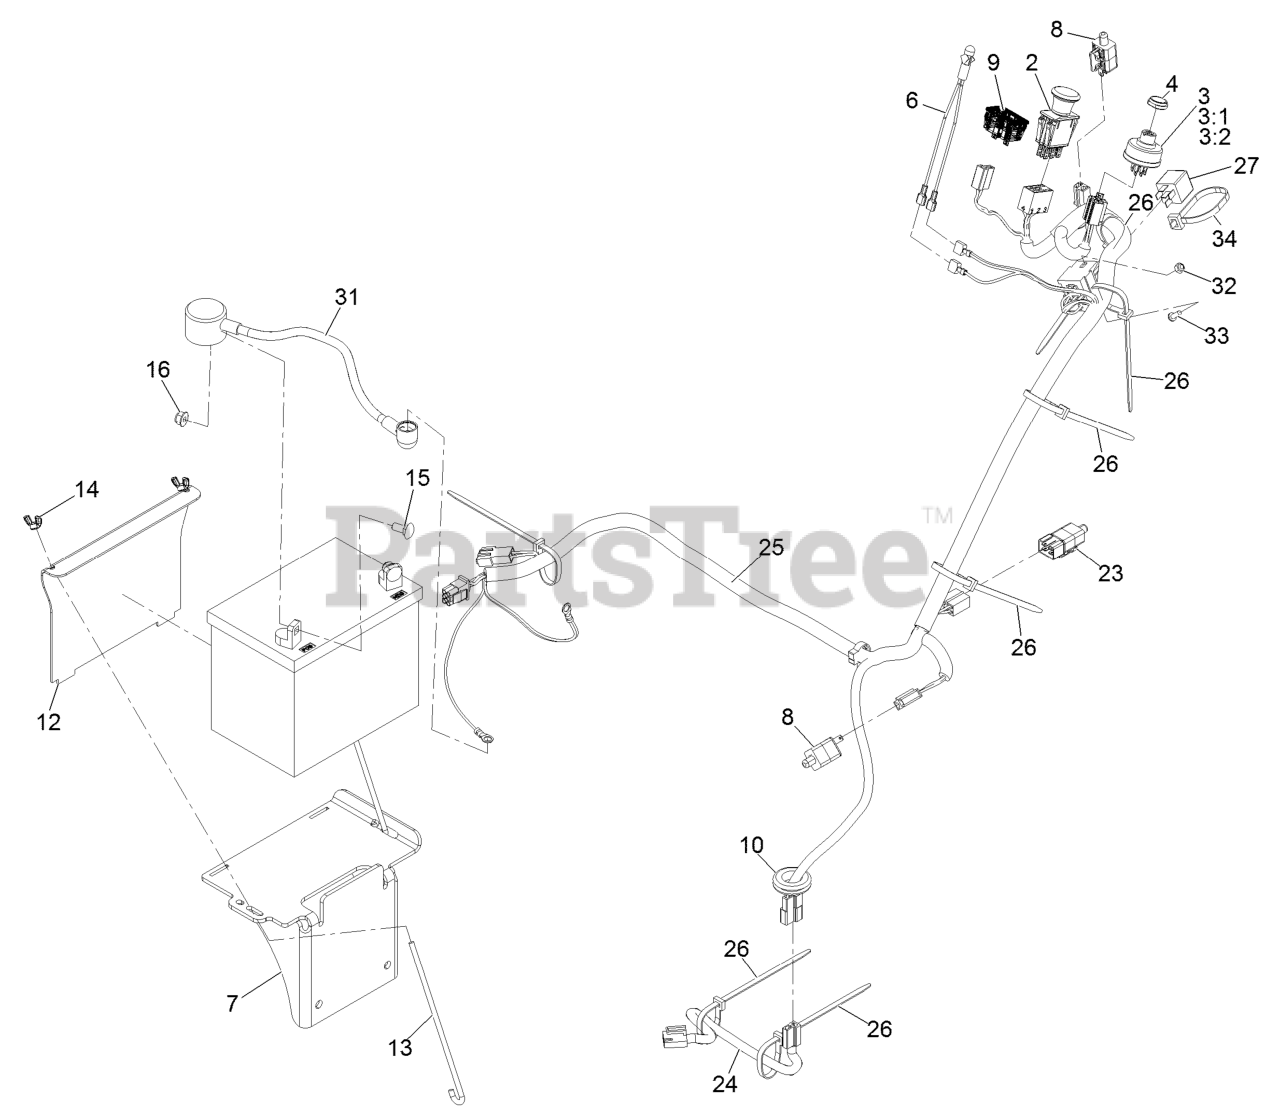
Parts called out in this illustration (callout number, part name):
2	SWITCH-PTO
3:1	WASHER-LOCK
4	NUT-SWITCH, IGNITION
6	INDICATOR-LED, RED
7	WELD, BATTERY MOUNT
9	METER-HOUR
10	GROMMET
12	BRACKET, BATTERY HOLD DOW
13	BOLT-HOLDDOWN
14	WINGNUT
15	BOLT-CARR
16	NUT-HF, NI
23	SWITCH, 2 POLE
24	HARNESS-CLUTCH PIGTAIL
25	HARNESS-MAIN
26	TIE-PLASTIC
31	ASM,POSITIVE BATTERY CABL
32	NUT-LOCK, NI
34	TIE-PLASTIC
